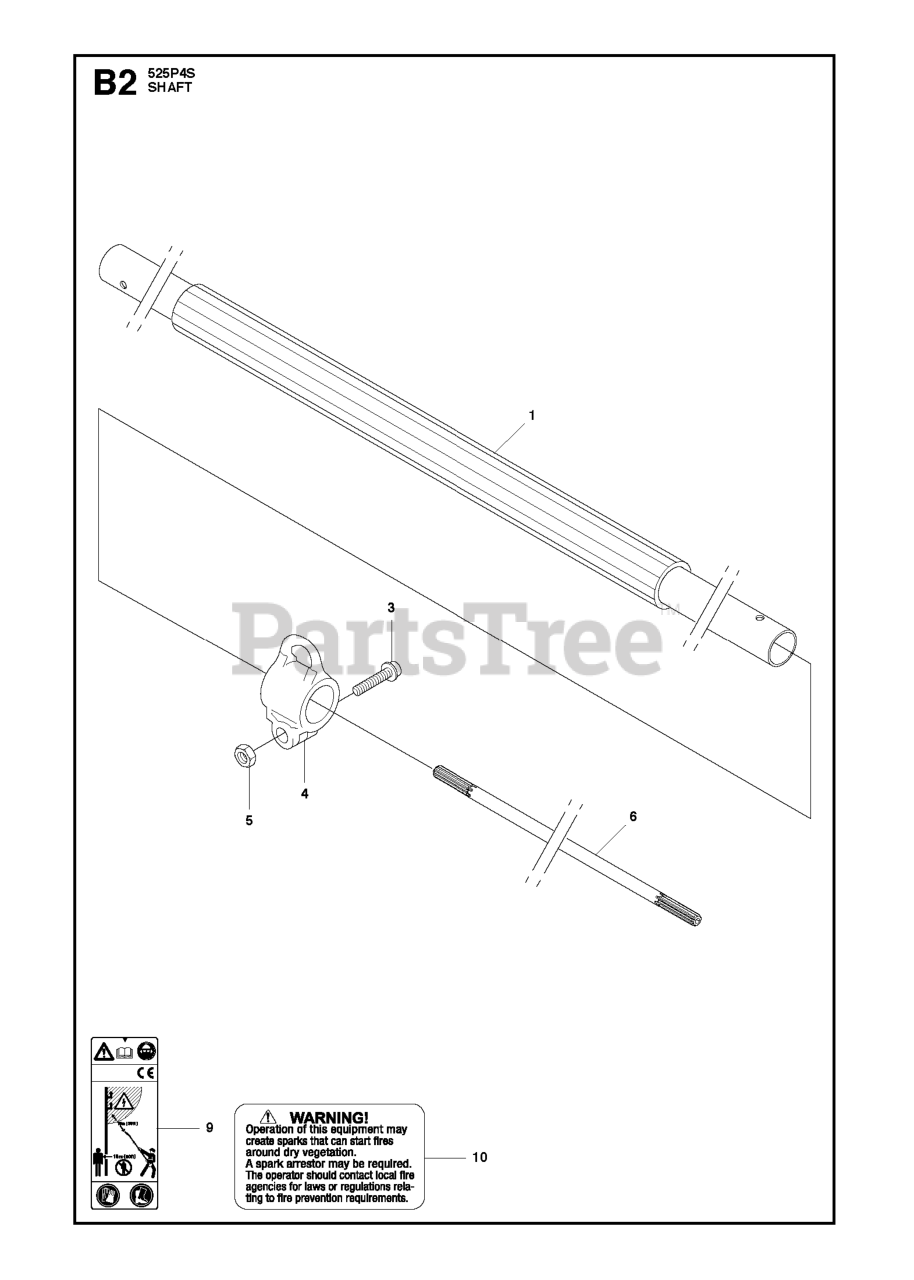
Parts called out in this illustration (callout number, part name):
1	TUBE
4	HARNESS HOLDER
6	DRIVESHAFT
9	DECAL WARNING SPARK ARRESTOR
10	DECAL SPARK ARRESTOR WARNING
